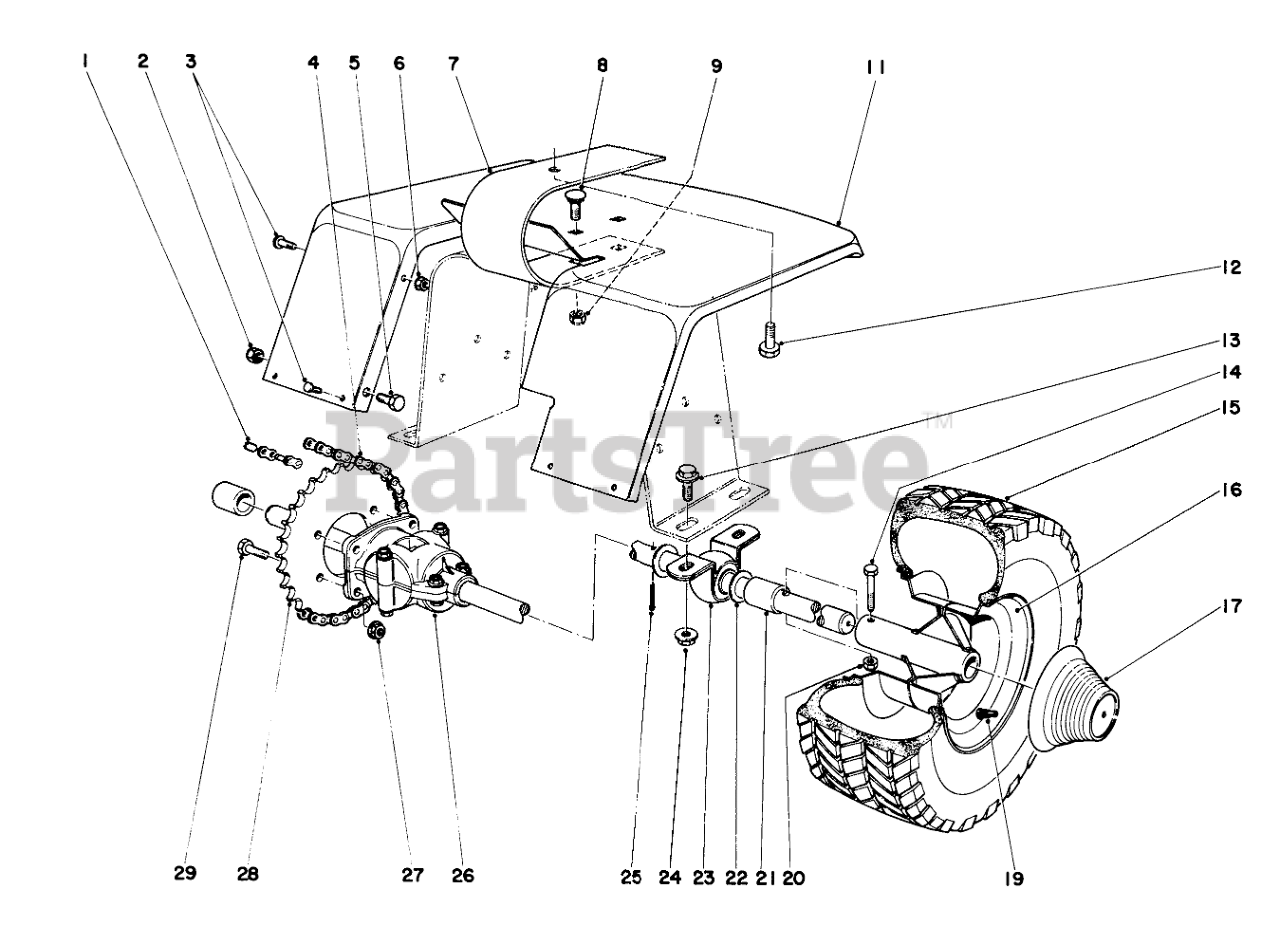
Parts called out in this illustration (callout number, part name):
1	LINK-CONNECTING
2	NUT-LOCK, CONE
3	10-24 X 3/8 PAN HD SC
4	Chain
5	SCREW-HH
6	NUT-KEPS
7	Seat Spring
8	BOLT-CARR
9	NUT-LOCK, CONE
11	Fender
12	Capscrew
13	SCREW-HHF
14	SCREW-HH
15	Tire
17	Hub Cap-Rear
19	STEM-VALVE
20	NUT-LOCK, SIDE
21	Tube-Rear Axle
22	WASHER
23	PILLOW BLOCK
24	NUT-HF
25	PIN-COTTER
26	Differential
27	NUT-HF
28	Sprocket
29	SCREW-HH
